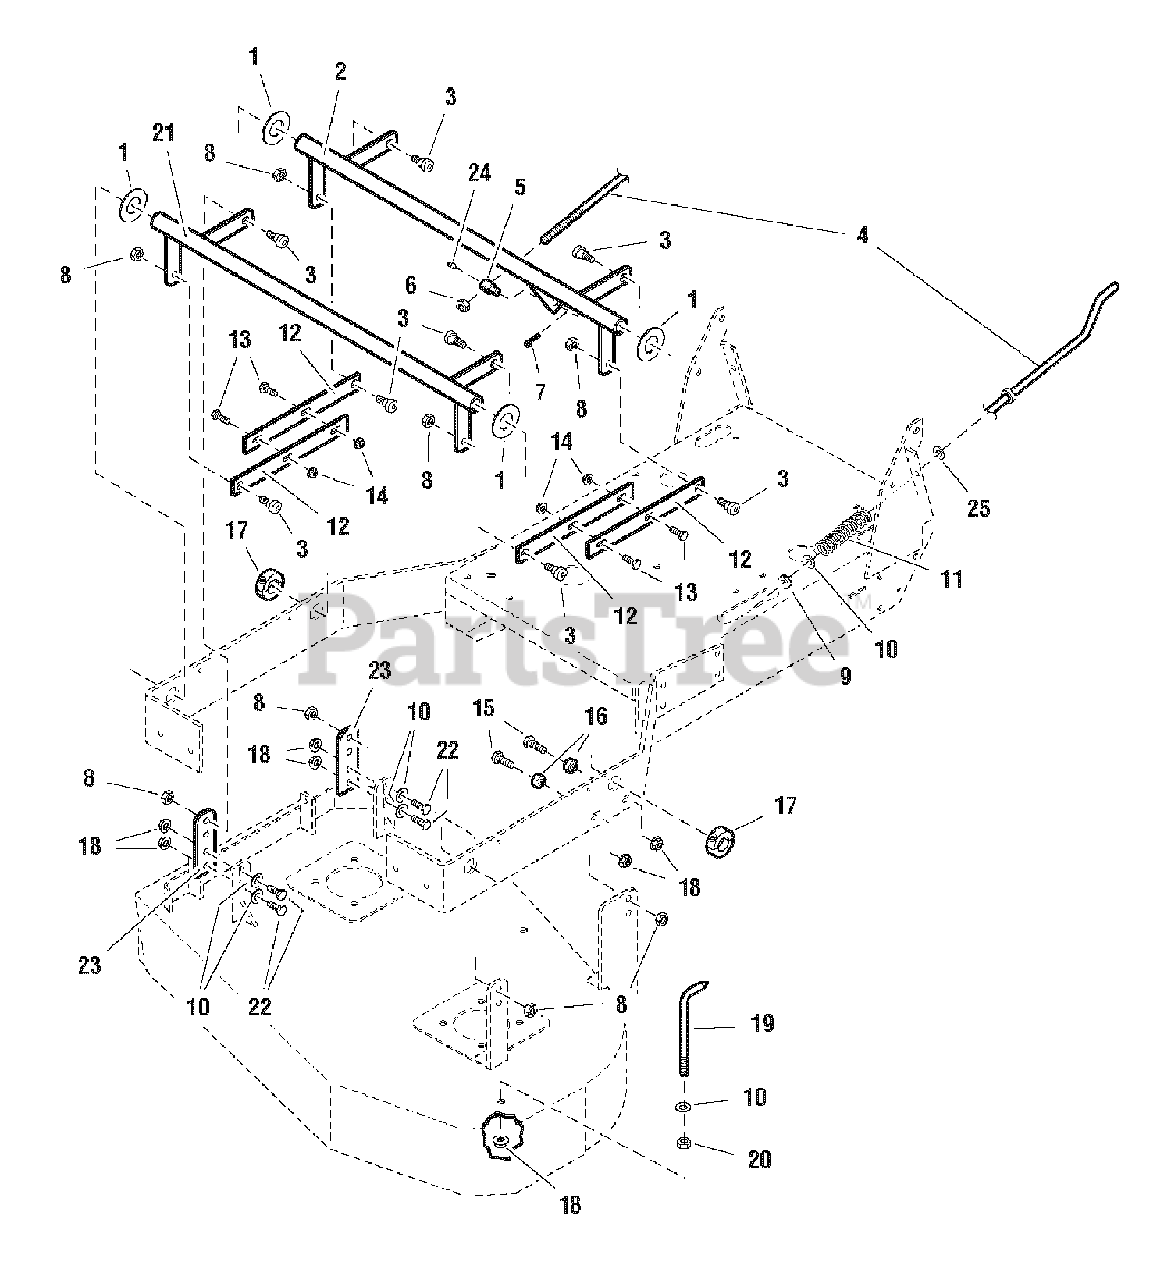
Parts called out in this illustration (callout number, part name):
1	WASHER, 1"
2	DECK LIFT PIVOT - REAR
3	SHOULDER BOLT, 3/8-16 x 1/2 x 3/8
4	HEIGHT ADJUST ROD
5	LINKAGE ADJUSTER
6	NUT, Hex Side Lock, 3/8-16
7	PIN, Cotter
8	NUT, Hex Top Lock, 3/8-16
9	COLLAR, Set, 3/8
10	WASHER, 3/8
11	SPRING, Compression
12	DECK ADJUST LINK
13	CAPSCREW, Hex Head, 5/16-18 x 1
14	NUT, Hex Serrated Flange, 5/16-18
15	BOLT, 3/8-16 X 1-1/4" GD5 CZ
16	SPACER
17	COLLAR, Double Split, 1"
18	NUT, Hex Serrated Flange, 3/8-16
19	CUT HEIGHT INDICATOR
20	NUT, Hex, 3/8-16
21	DECK LIFT PIVOT - FRONT
22	BOLT, 3/8-16 X 3/4" GD5 CZ
23	HANGER PLATE
24	GREASE FITTING, 1/4-28
25	WASHER, Nylon, 3/8
